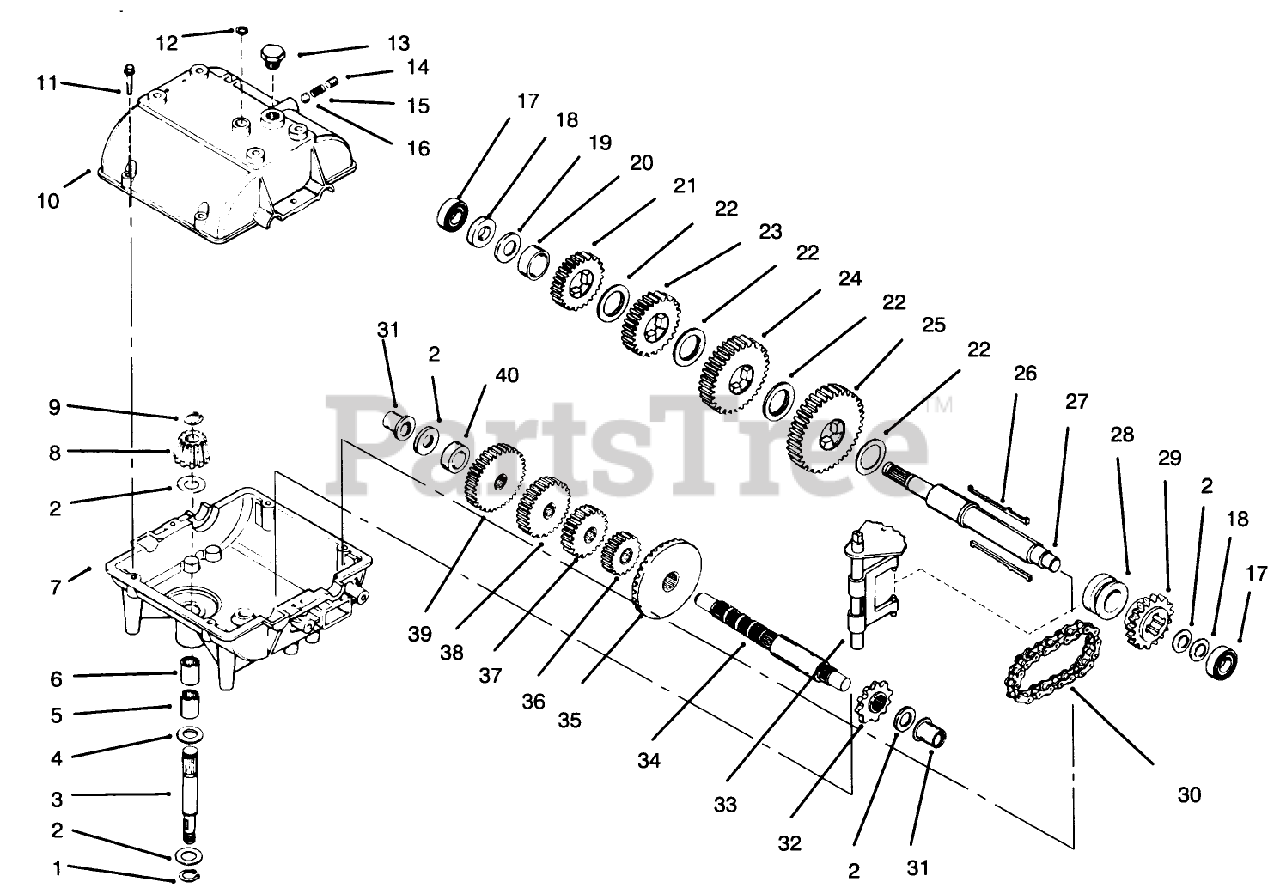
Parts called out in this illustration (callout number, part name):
1	Ring-Snap
2	Washer
3	Shaft-Input
4	O Ring
5	Bearing-Needle
6	Bearing-Needle
7	Case-Transmission
8	Bevel Pinion-Input
9	Ring-Retainer
10	Cover-Transmission
11	Ring Set (.020 O S)
12	Cut Seal-Square
14	Screw-Set
15	Spring
16	Ball-Steel
17	Bearing-Ball
18	Thrust Washer
19	Washer
20	Spacer
21	Gear-Spur, 25 Teeth
22	Washer
23	Gear-Spur 27 Teeth
24	Gear-Spur, 30 Teeth
25	Gear-Spur, 35 Teeth
27	Shaft-Output/Brake
28	Collar-Shift
29	Sprocket-18 Teeth
30	Chain-Roller #41
31	Bushing-Flange
32	Sprocket-9 Teeth
33	Rod and Fork ASM
34	Countershaft
35	Gear-Bevel, 42 teeth
36	Gear-Spur 15 Teeth
37	Gear-Spur, 20 Teeth
38	Gear-Spur 23 Teeth
39	Gear-Spur, 25 Teeth
40	Spacer
